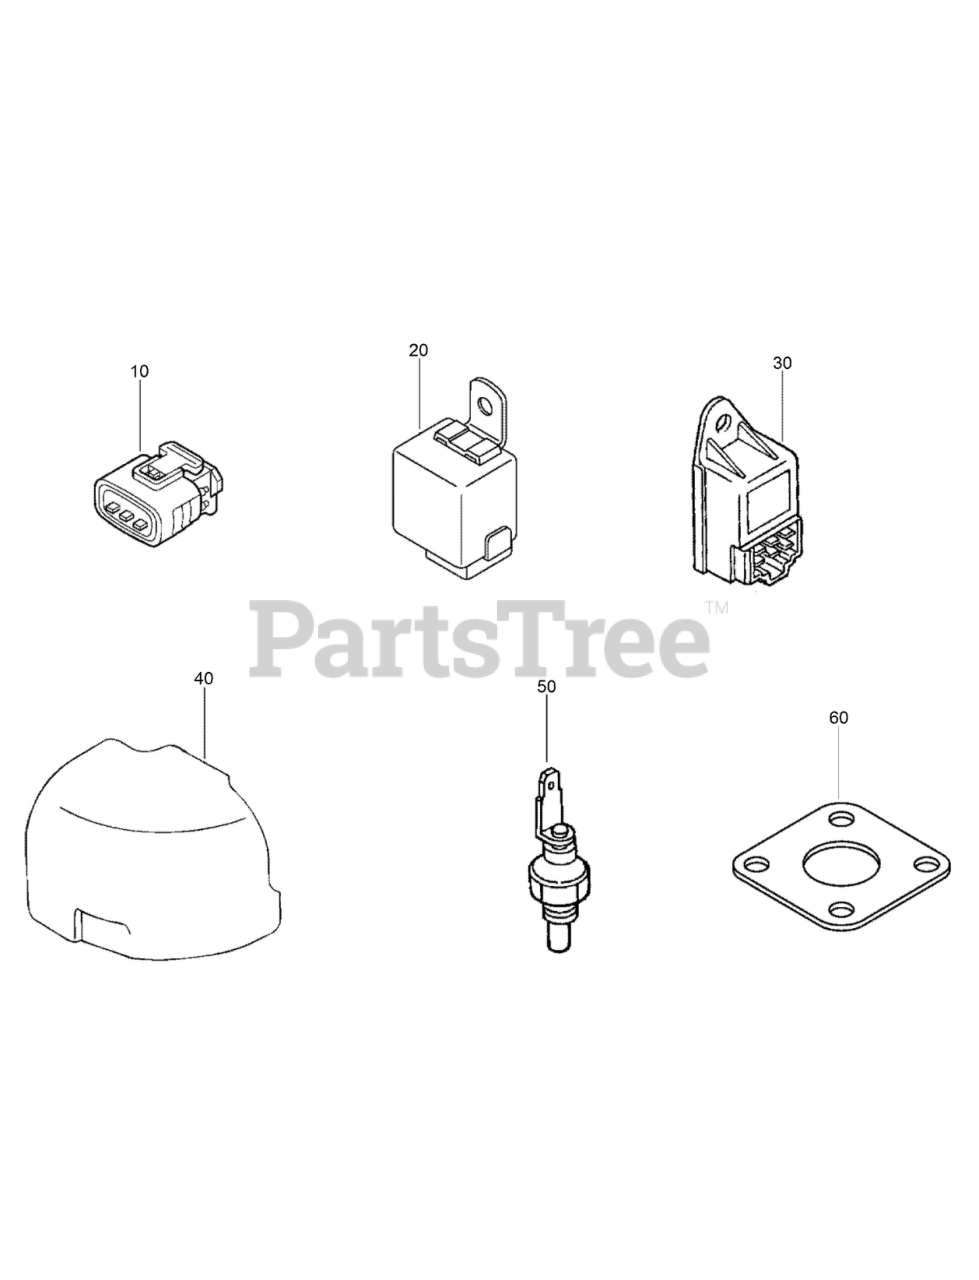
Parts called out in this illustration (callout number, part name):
10	CONNECTOR ASM
30	TIMER-LAMP, GLOW
40	COVER-HEAT
50	SENSOR, COOLANT-TEMP
60	GASKET-MUFFLER
